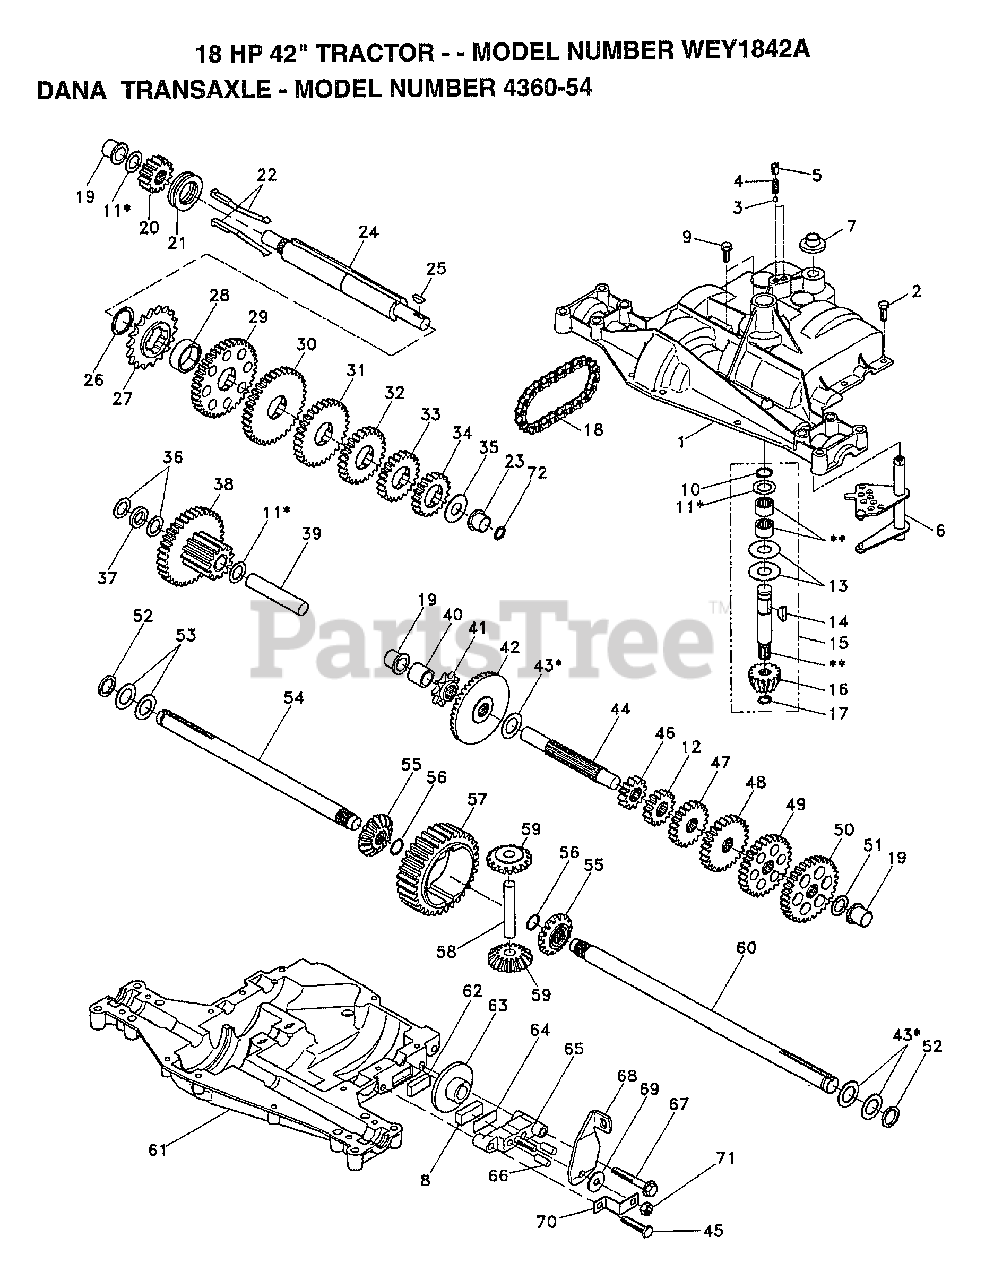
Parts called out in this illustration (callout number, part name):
4	"SPRING, DETENT LT"
5	"SCREW, SET LT"
6	SHIFTER.ASM.KIT.
7	SHIFTER BOOT
8	PUCK T
9	SCREW TAP W/SEAL
10	RETAINING RING LT
11	ASM KIT SHIM 4689
13	WASHER T
14	WOODRUFF KEY
17	"RING,RETAINING LT"
18	"CHAIN,24 PTCH LT"
19	BEARING.FLNG.5510
20	GEAR SPUR 14T
21	COLLAR CLUTCH
22	KIT.ASM.CLUTCH KY
23	"FLANGE, BEARING"
24	SHAFT INTERM
25	WOODRUFF KEY
26	"RING,RETAINING LT"
27	SPROCKET 18T T
28	SPACER YT
29	KIT.GEAR.12/37TH
31	GEAR SPUR 30T
32	GEAR 25T LT
33	GEAR SPUR 22 TT
34	SPUR GEAR 19T
35	"WASHER, PLAIN LT"
36	WASHER 025
37	SPACER
38	ASSM GEAR COMB
39	SHAFT IDLER
40	SPACER T
41	SPROCKET 9T LT
43	ASM KIT SHIM
44	SHAFT T
45	"SCREW, TAPPING LT"
48	"GEAR, SPUR 25T LT"
49	GEAR 28T T
50	"GEAR, SPUR 31T LT"
51	WASHER 060
52	NEOPRENE WASHER
53	WASHER 031
55	GEAR LT
56	"RING,RETAINING LT"
58	SHAFT T
59	"GEAR,MITER 15T YT"
62	PUCK T
63	BRAKE DISC. T
64	SPACER LT
66	PIN T
69	WASHER LT
71	NUT.LOCK.5/16-24
72	SQUARE RING
